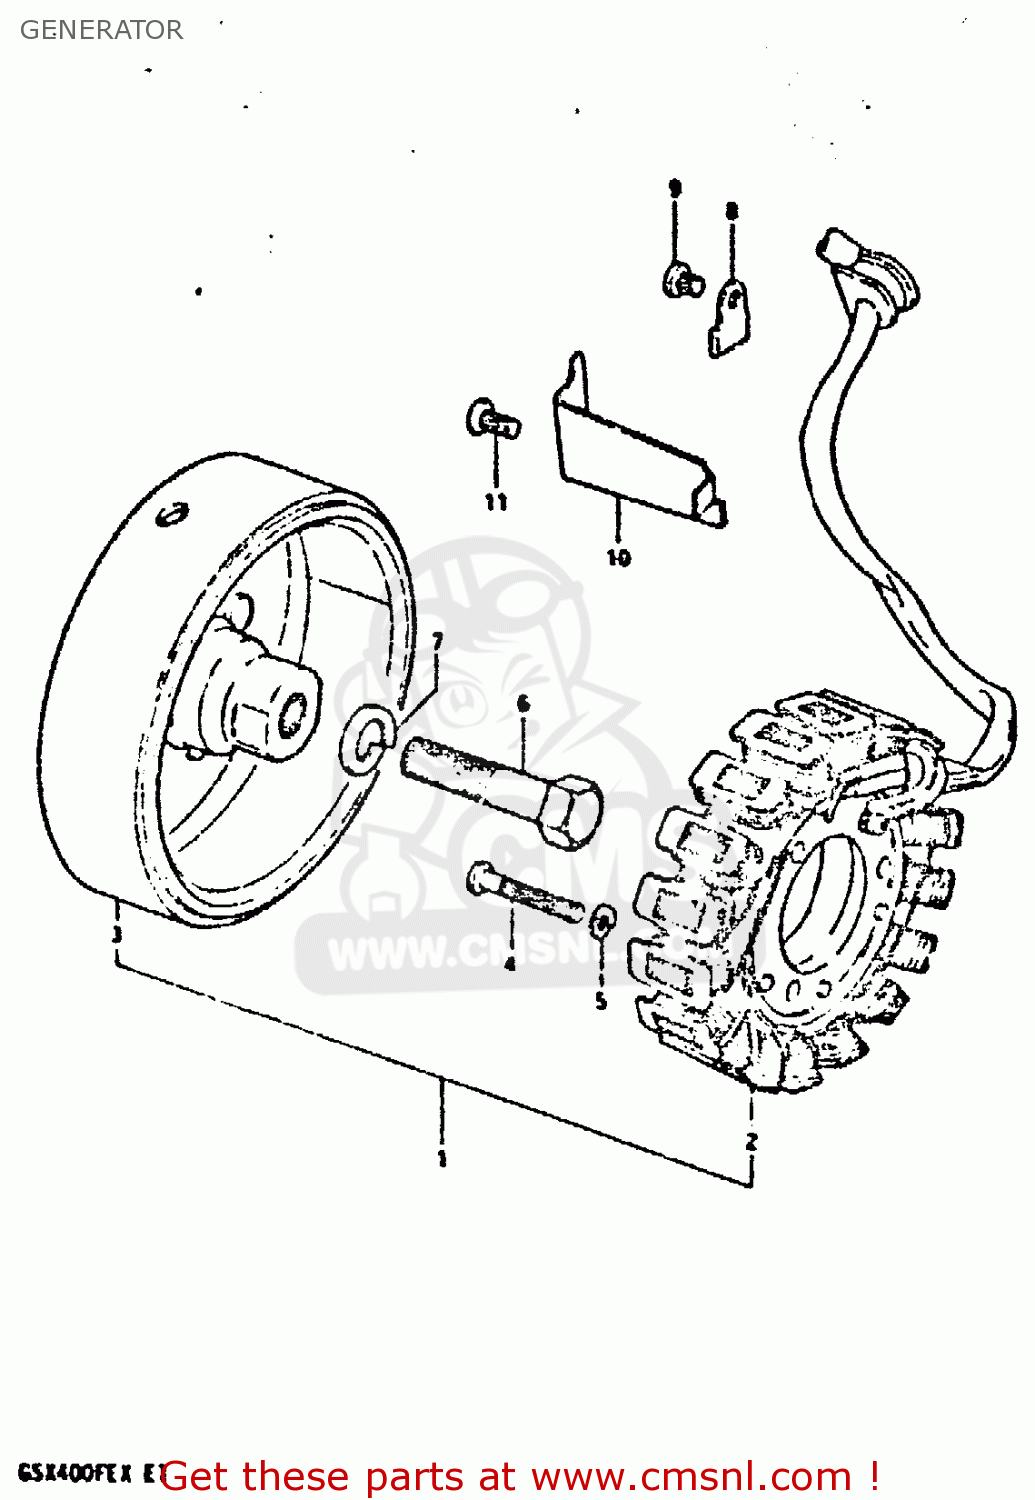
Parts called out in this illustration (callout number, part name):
1	GENERATOR ASSY
2	STARTOR
3	ROTOR ASSEMBLY
4	SCREW
5	LOCK WASHER
6	BOLT 12X45
7	WASHER,LOCK 12
8	CLAMP,GENERATOR LEAD WIRE
9	SCREW
10	CLAMP,GENERATOR LEAD WIRE
11	SCREW
